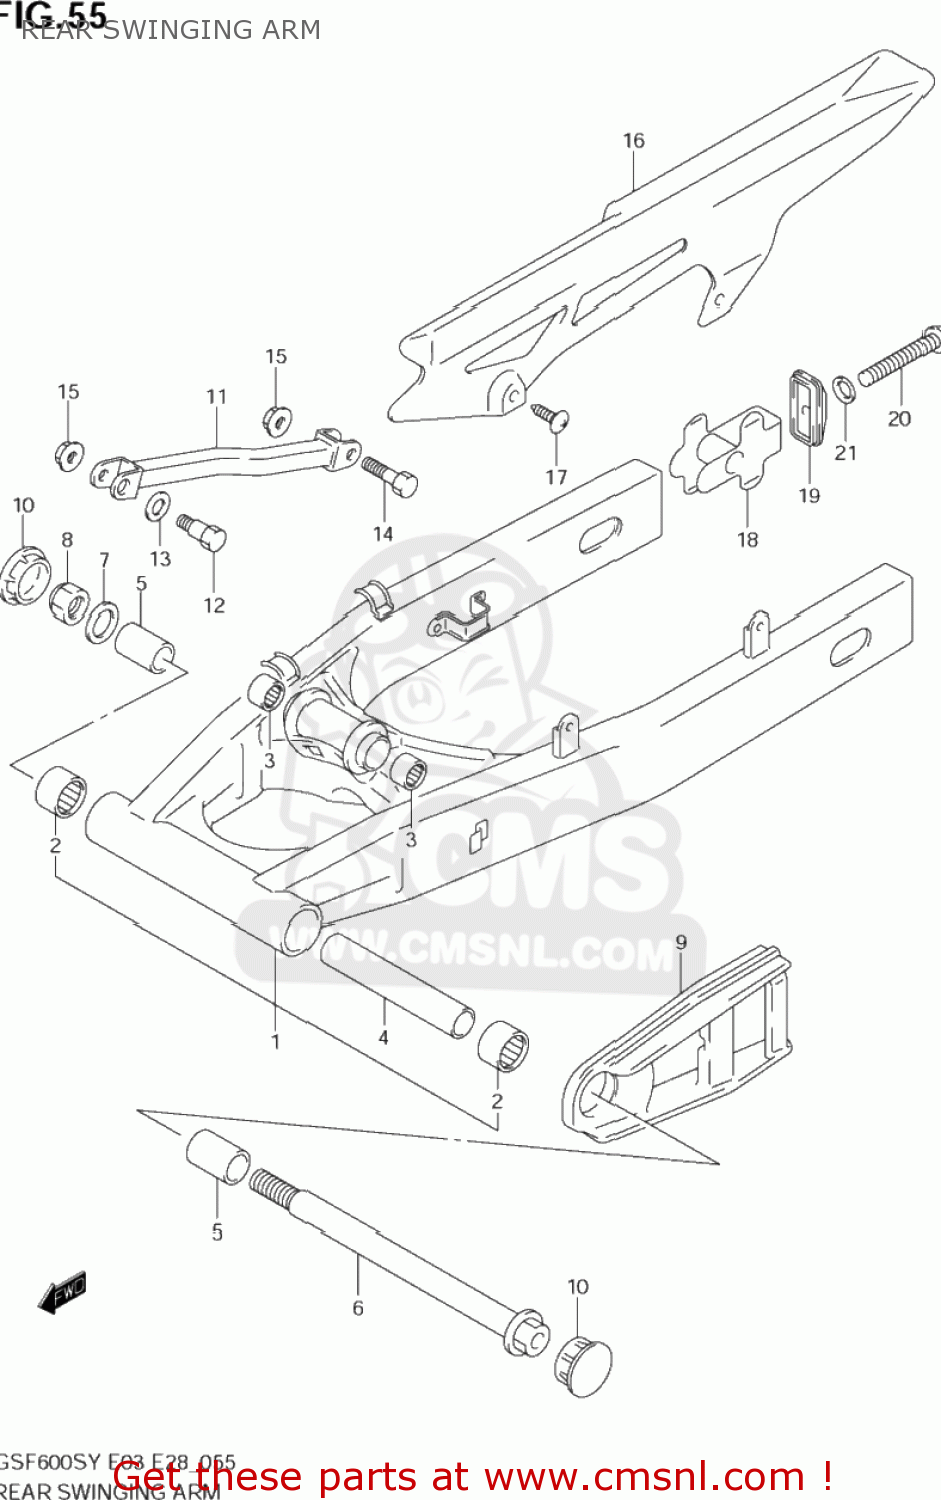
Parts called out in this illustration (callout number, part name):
1	SWINGINGARM ASSY,RR
2	BEARING(25X33X35)
3	BEARING(17X24X25)
4	SPACER(20.8X27.2X146)
5	SPACER,RR SWGARM PIVOT
6	SHAFT,RR SWINGINGARM PIVOT
7	WASHER(18.5X28X2.6)
8	NUT
9	BUFFER,CHAIN TOUCH DEFENSE
10	CAP,FRAME BODY
11	TORQUELINK,RR
12	BOLT(10X39)
13	WASHER(12.5X20X1)
14	BOLT(10X34)
15	NUT
16	CASE,CHAIN
17	SCREW(6X16)
18	ADJUSTER,CHAIN
19	PLATE,CHAIN ADJUSTER GUIDE
20	BOLT(8X50)
21	WASHER
